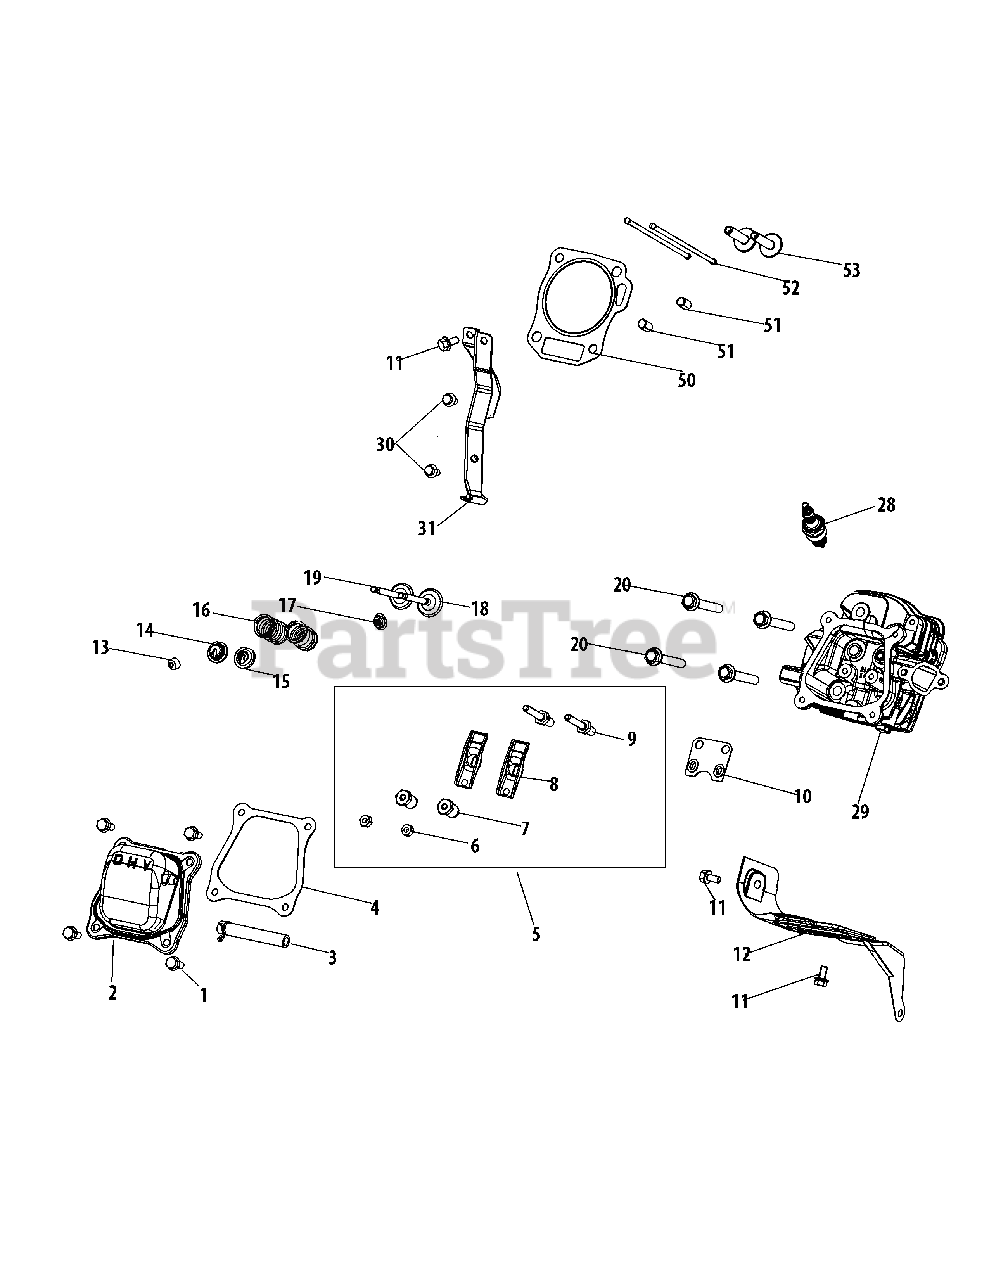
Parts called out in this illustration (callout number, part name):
1	Bolt, M6×16
2	Valve Cover
3	Breather Hose
4	Gasket, Valve Cover
5	Rocker Arm Assembly
6	Lock Nut
7	Adjust Nut
8	Rocker Arm
10	Rocker Arm Base
11	Bolt, M6×12
12	Shroud
13	Valve Adjust Cap, Exhaust
14	Valve Spring Seat
15	Valve Spring Seat
16	Valve Spring
17	Intake Valve Seal
18	Intake Vavle
19	Exhaust Valve
20	Bolt, M8×55
28	Spark Plug
29	Cylinder Head
30	Bolt, M6×12
31	Snow Guard
50	Gasket, Cylinder Head
51	Pin, 10×16
52	Push Rod
53	Tappet
